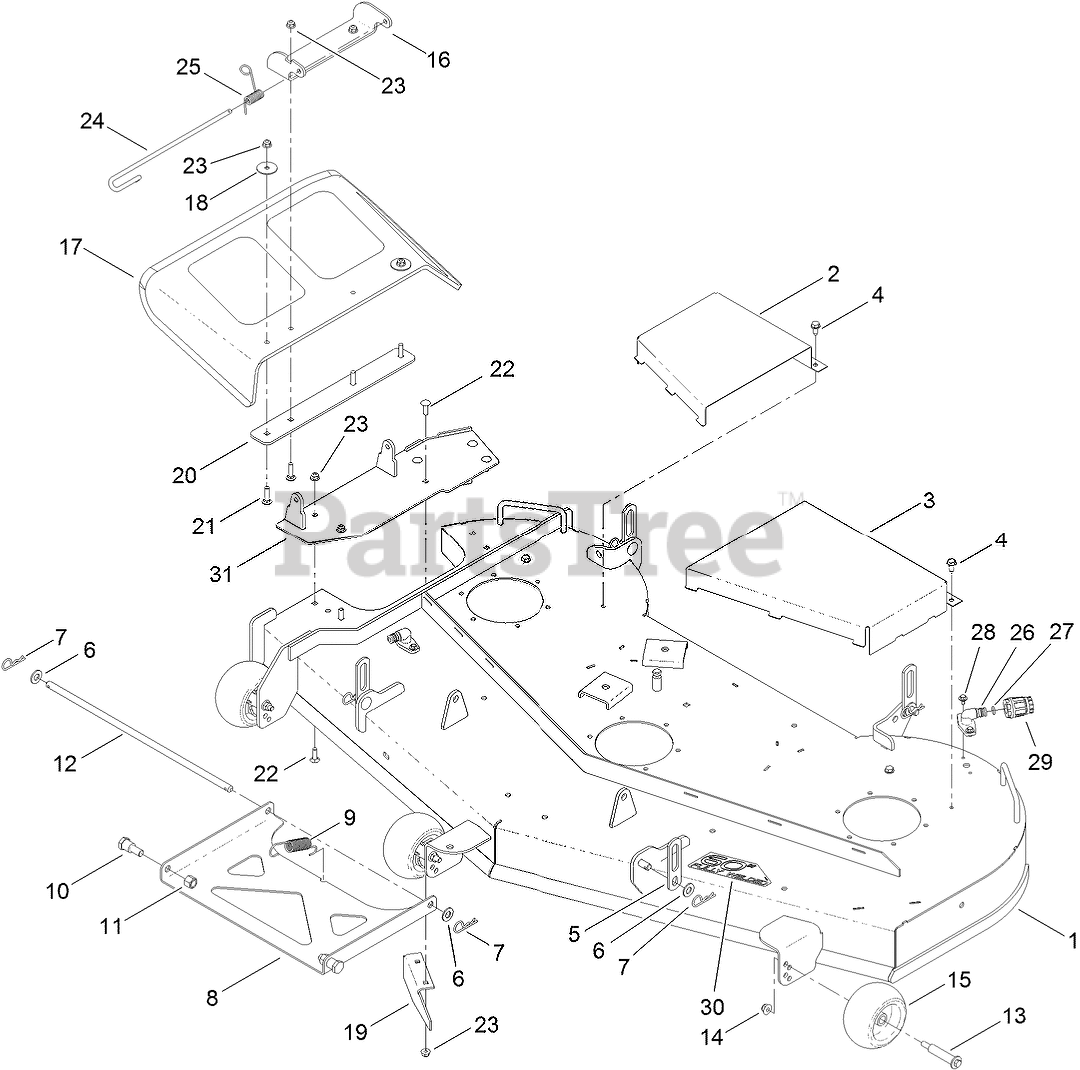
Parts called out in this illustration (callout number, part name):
1	60 INCH DECK AND DECAL ASM
2	COVER-BELT, RH
3	COVER-BELT, LH
4	SCREW-HWHTF
5	LINK-LIFT
6	WASHER-FLAT
7	PIN-COTTER
8	PAN-PIVOT, DECK
9	SPRING-EXTENSION
10	BOLT-SHOULDER, HH
11	NUT-LOCK, NI
12	ROD-DECK, PIVOT
13	BOLT-SHOULDER
14	NUT-HF, NI
15	ROLLER-SCALP, ANTI
16	BRACKET-DEFLECTOR, UPPER
17	DEFLECTOR
18	WASHER-FLAT
19	BAFFLE-CUTOFF
20	PLATE-DEFLECTOR
21	SCREW-CARR
22	SCREW-CARR
23	NUT-HF, NI
24	PIN-CHUTE
25	SPRING-TORSION
26	FITTING-WASHOUT
27	O-RING
28	SCREW-HHFTF
29	CONNECTOR-HOSE
